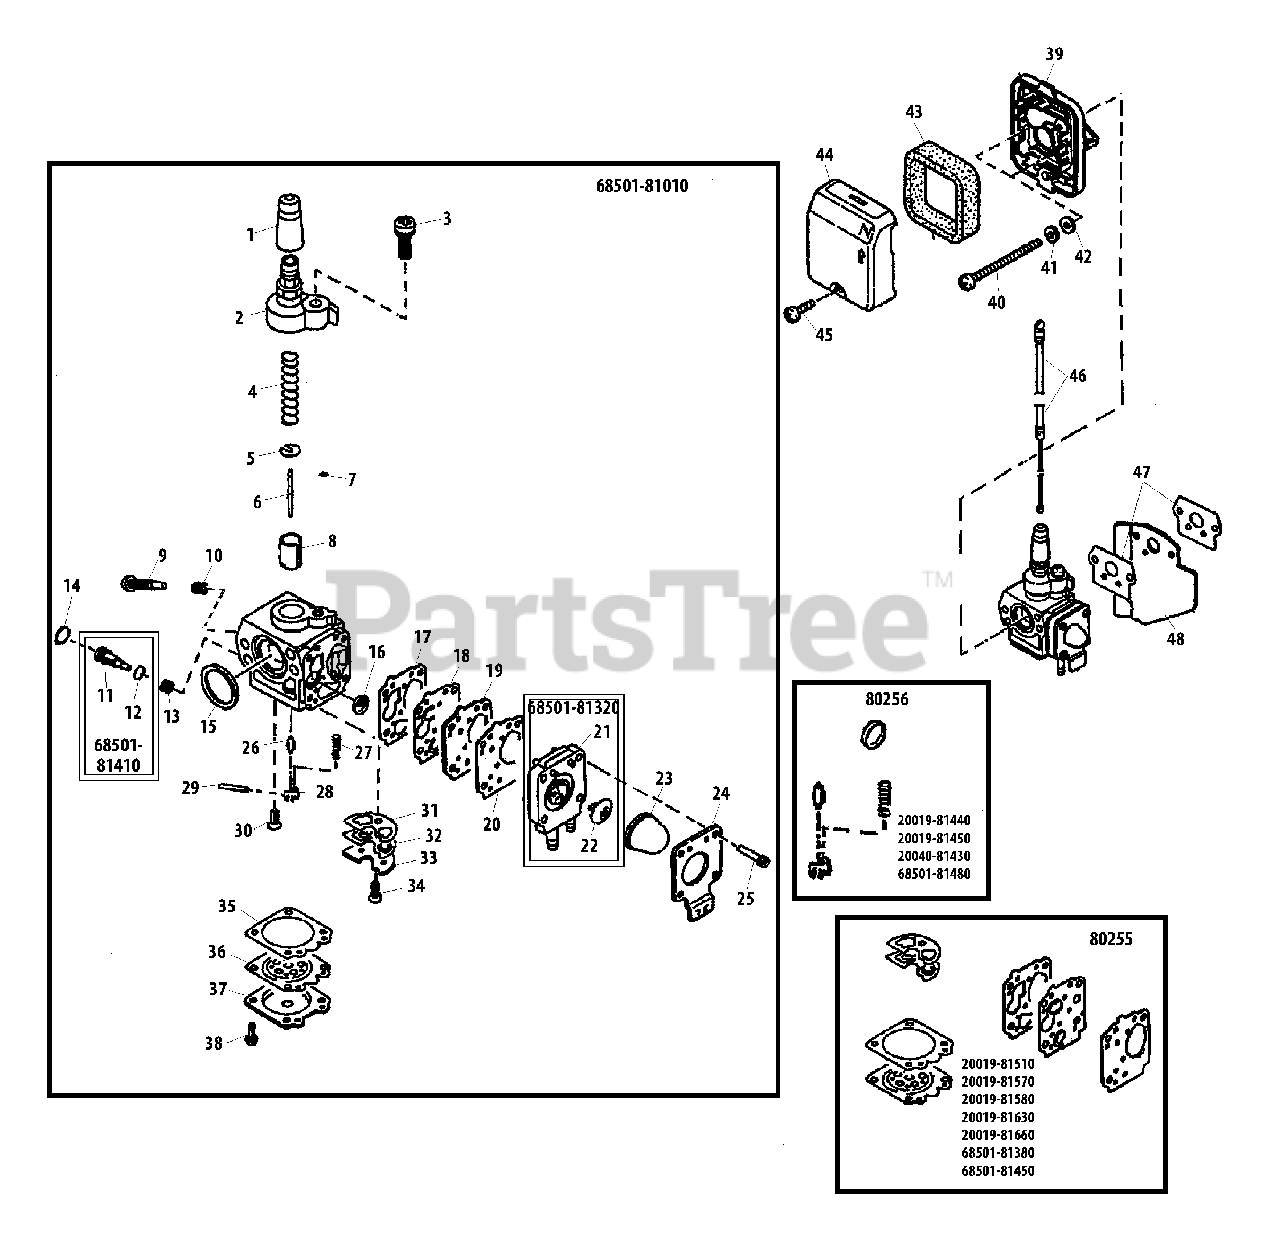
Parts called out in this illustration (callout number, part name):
1	GROMMET
2	CAP, CARBURETOR
3	SCREW
4	SPRING
5	WASHER, SPRING SUPPORT
6	NEEDLE, JET
7	NEEDLE, JET
8	VALVE, SLIDE
9	SCREW, IDLE ADJUST
10	SPRING
11	MAIN ADJUST SCREW
14	PLATE
15	RING, PACKING
16	SCREEN, FUEL INLET
17	GASKET, PUMP
18	DIAPHRAGM, FUEL PUMP
19	PLATE, PUMP
20	GASKET, FUEL PUMP
21	COVER, PUMP
22	VALVE
23	BULB, PURGE
24	COVER, PUMP
25	SCREW M3×14
26	VALVE, INLET NEEDLE
27	SPRING
28	LEVER, METERING
29	PIN, METERING LEVER
30	SCREW M3×8
31	GASKET
32	VALVE, CHECK
33	PLATE
34	SCREW M3×8
35	GASKET, METERING DIAPHRAGM
36	DIAPHRAGM, METERING
37	COVER, DIAPHRAGM
38	SCREW M3×8
39	CASE, AIR FILTER
40	SCREW
41	WASHER, SPRING 5
42	WASHER, FLAT 5.5×10×0.8
43	FILTER, AIR
44	COVER, AIR FILTER
45	SCREW M5×16
46	CABLE, THROTTLE
47	GASKET, CARBURETOR
48	GASKET, INTAKE
68501-81010	CARBURETOR
68501-81320	COVER ASSY, PUMP
68501-81410	SCREW, MAIN ADJUST
80255	GASKET / DIAPHRAGM KIT
80256	REPAIR KIT, CARBURETOR
